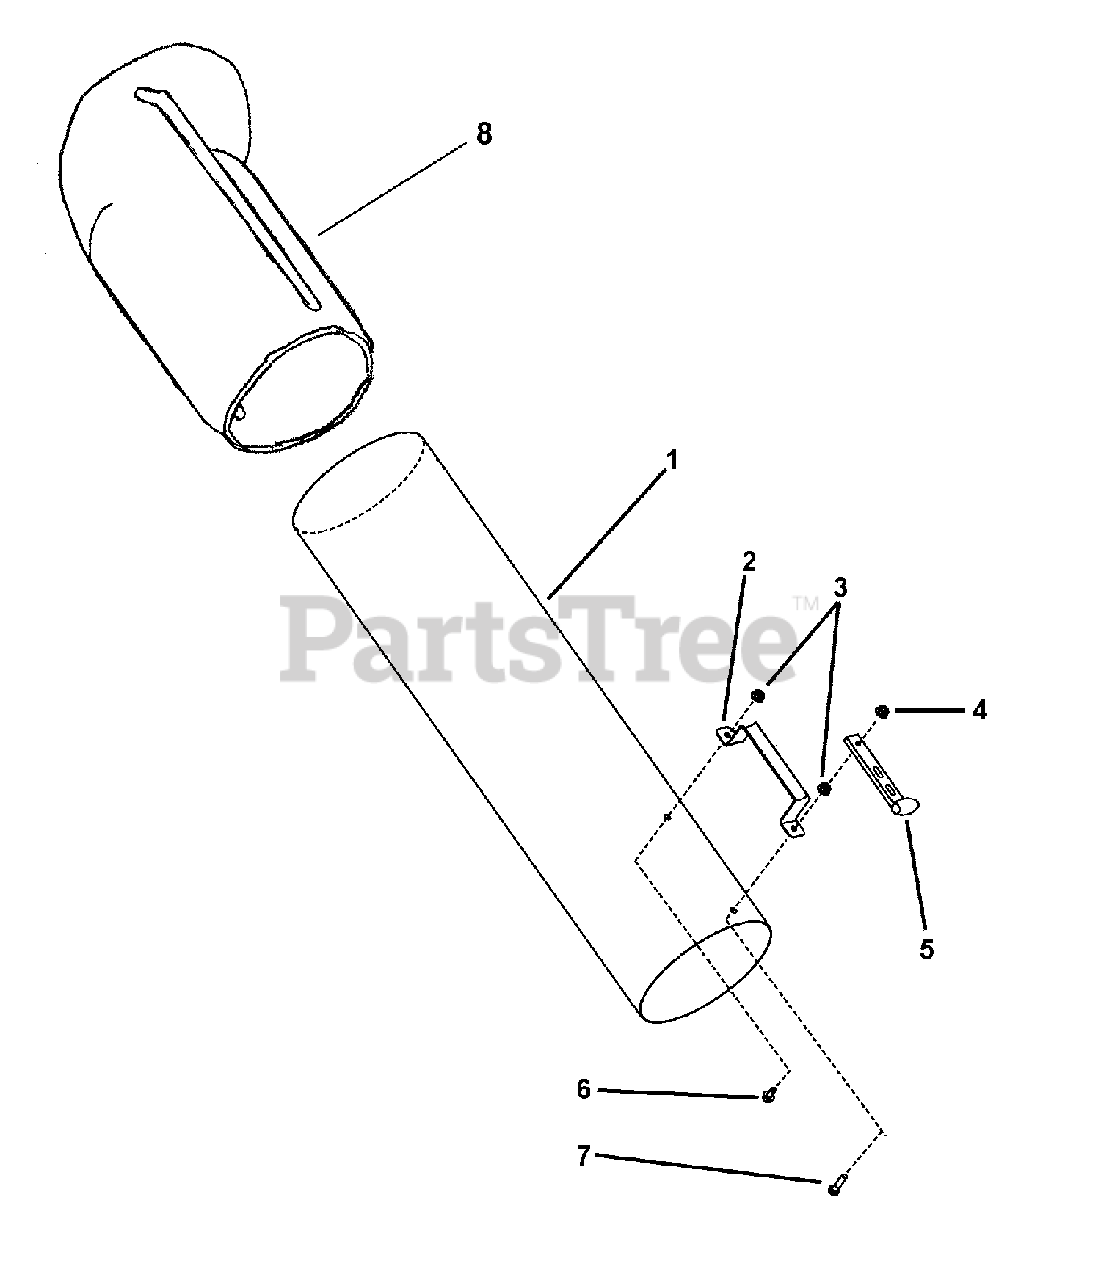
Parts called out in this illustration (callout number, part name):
1	TUBE, GRASS CATCHER 42", CLEAR POLY
1	TUBE, GRASS CATCHER 46" & 52", CLEAR POLY
2	HANDLE, TUBE, GRASS CATCHER
3	LOCKNUT, 1/4-20 KEPS
4	NUT, CENTER LOCK FLANGE 1/4-20
5	STRAP, RUBBER
6	SCREW, 1/4-20 X 1/2 SLOTTED
7	SCREW, 1/4-20 X 1
8	ELBOW, UPPER TUBE 42"
8	ELBOW, UPPER TUBE 46" & 52"
